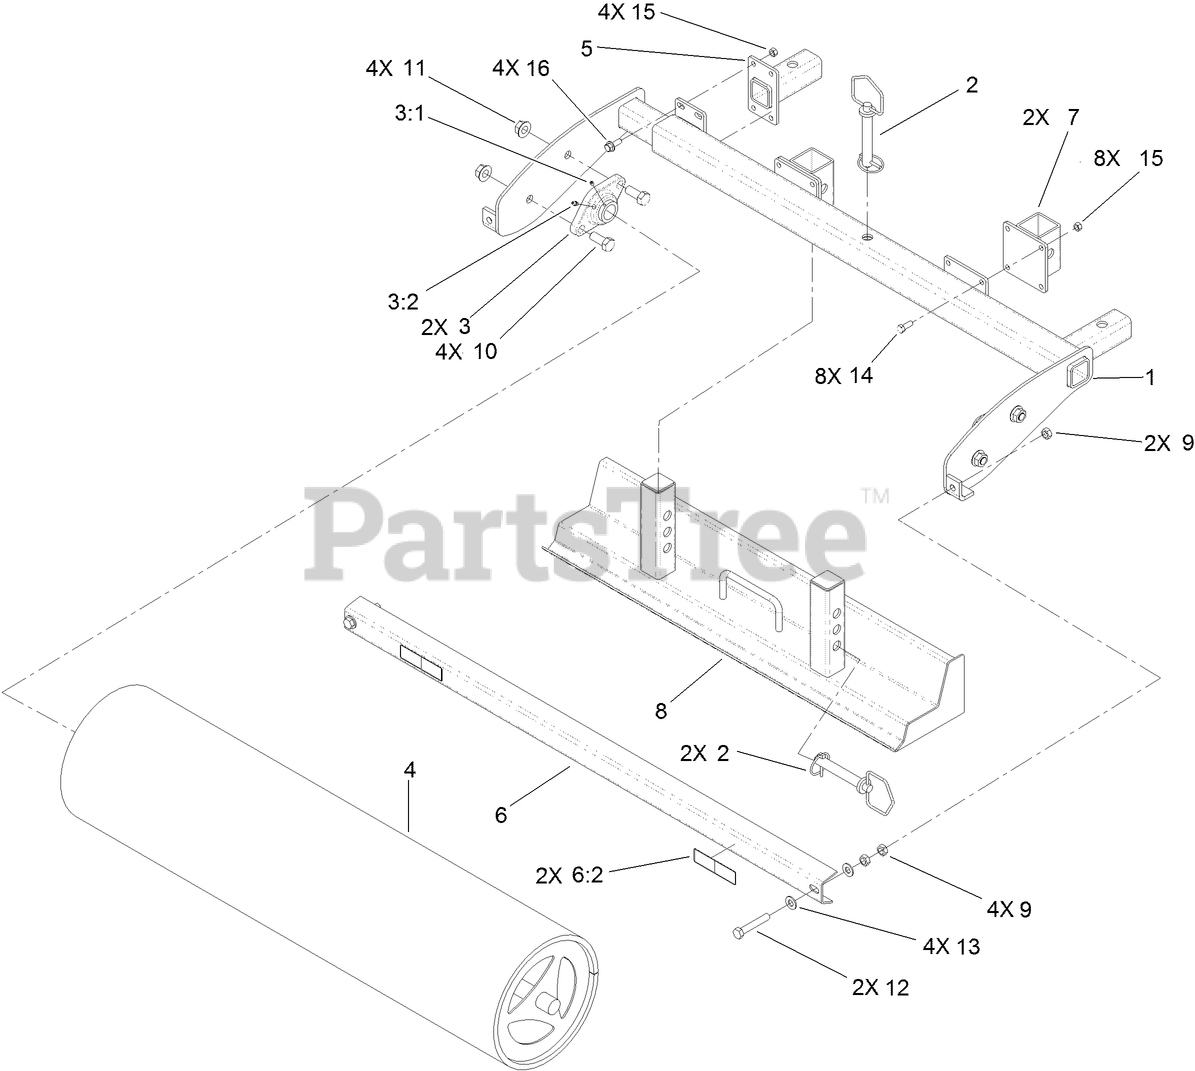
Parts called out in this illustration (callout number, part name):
1	ROLLER FRAME ASM
2	PIN-DRIFT
3	BEARING ASM
3:1	SCREW-SET, HSH
3:2	FITTING-GREASE
4	ROLLER-MESH
5	ARM-MALE
6	SCRAPER PLATE ASM
6:2	DECAL-WARNING
7	SCRAPER GUIDE ASM
8	BLADE-GRADER
9	NUT-HEX
10	SCREW-HH
11	NUT-FLANGE
12	SCREW-HH
13	WASHER-FLAT
14	SCREW-HH
15	NUT-HEX
16	SCREW-HHF
